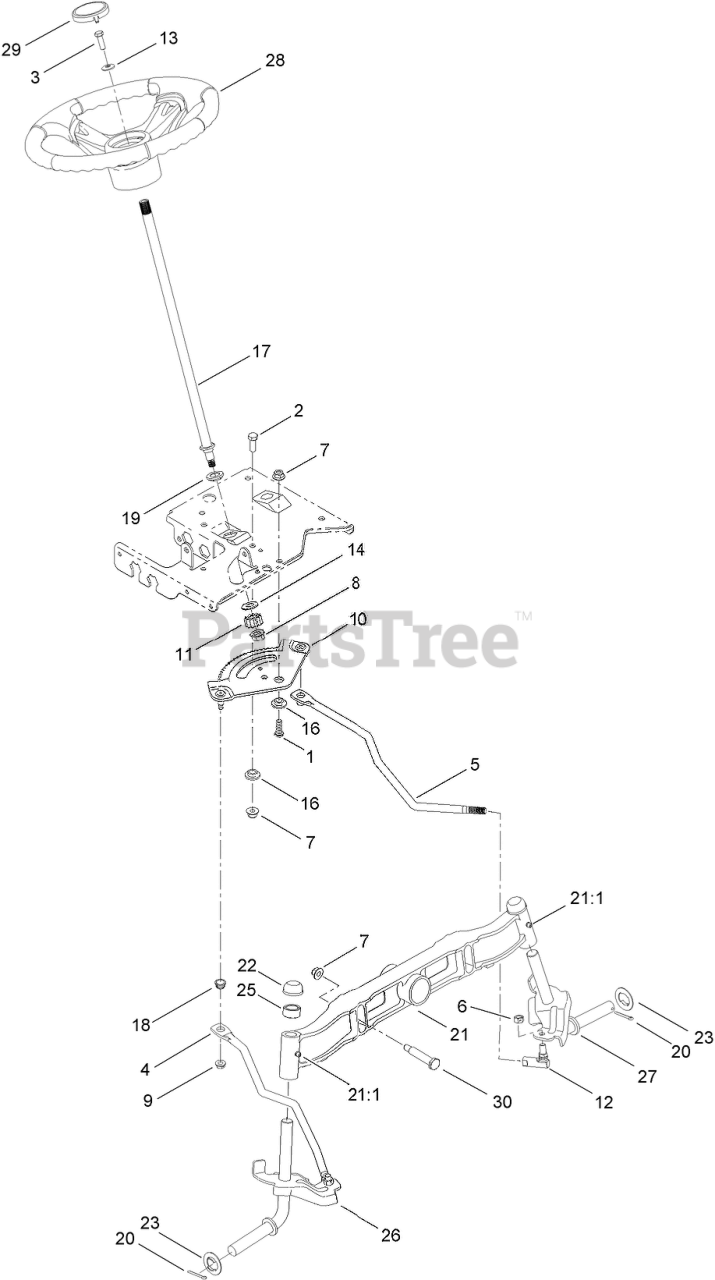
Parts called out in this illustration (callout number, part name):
1	SCREW-HH
2	SCREW-HH
3	SCREW-HH
4	LINK-DRAG, RH
5	LINK-DRAG, LH
6	NUT-HEX, LOCK
7	NUT-LOCK, FLANGE
8	NUT-LOCK, FLANGE
9	NUT-LOCK, FLANGE
10	GEAR-STEERING
11	GEAR-PINION, STEERING
12	BALL JOINT ASM
13	WASHER-FLAT
14	WASHER-FLAT
16	SPACER-SHOULDER
17	SHAFT-STEERING
18	BUSHING
19	BEARING-FLANGE, HEX
20	PIN-COTTER
21	PIVOT-AXLE, CAST IRON
21:1	FITTING-GREASE
23	WASHER-FLAT
25	SPACER
26	RH AXLE ASM
27	LH AXLE ASM
28	WHEEL-STEERING, SOFTGRIP
29	CAP-WHEEL, STEERING
30	BOLT-SHOULDER
